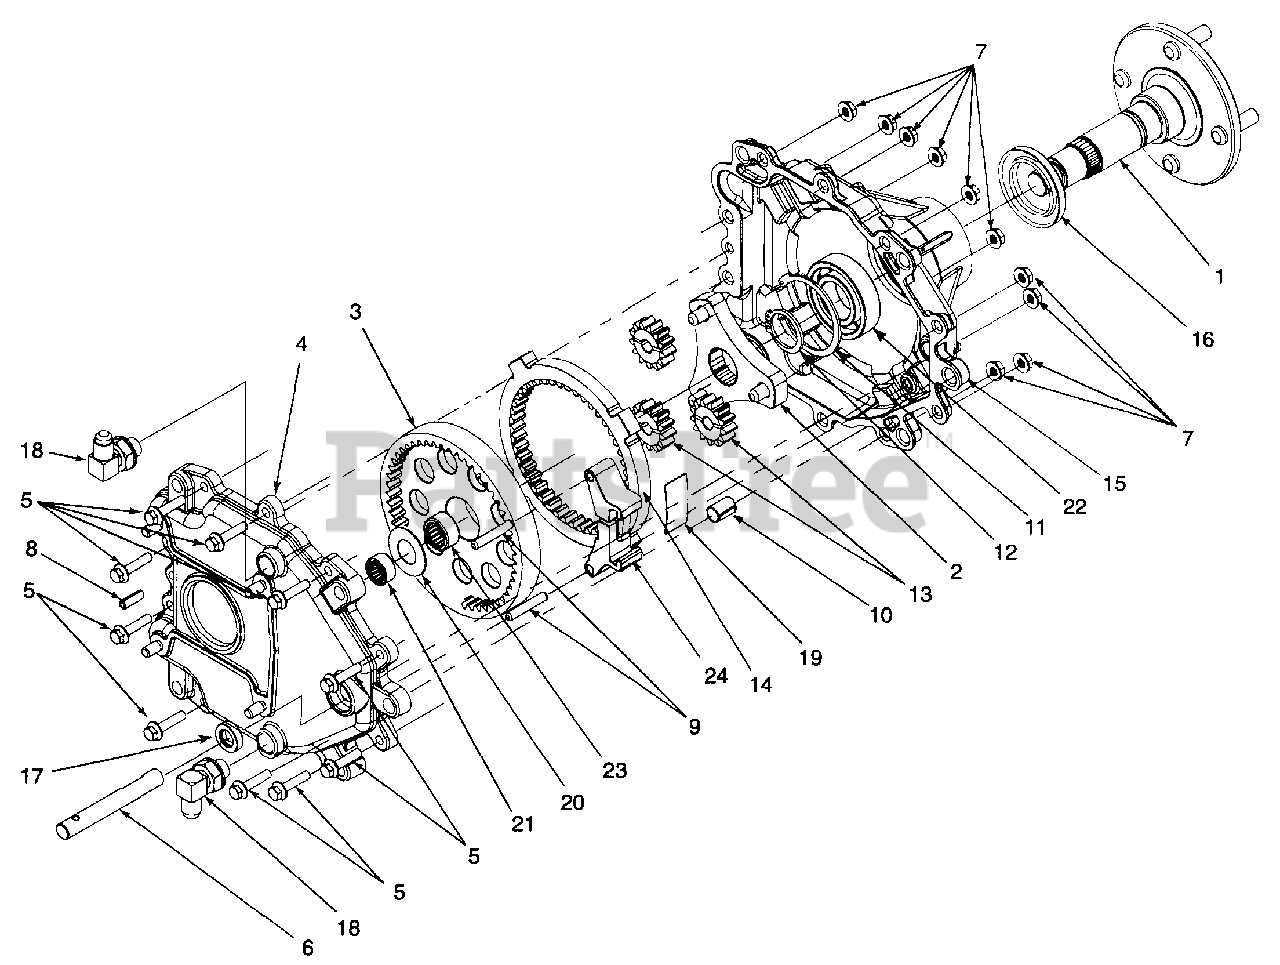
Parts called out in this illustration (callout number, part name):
1	Axle Assembly Stud, Ribbed Neck
2	Carrier Assembly, Output
3	Gear Assembly, 51T Internal & 20T
4	Housing Ass'y, Inner
5	Screw, Hex Wash. Hd. 1/4-20 x 1-1/8
6	Shaft, Brake
7	Nut, Hex Flange Lock, 1/4-20
8	Pin, Roll, .25 x .75
9	Pin, Dowel, .250 x 1.50
10	Bushing, Dowel
11	Ring, Inverted Retaining
12	Ring, Snap, 1.189 Dia. Shft.
13	Gear, Spur, 13T
14	Gear, Ring, 46T
15	Housing
16	Seal, Oil
17	Seal, Oil
18	Fitting, Elbow, 3/8 x 3/8
19	Spring, Brake Shoe
20	Washer, Shim, .76 x 1.5 x .030
21	Bearing, Needle
22	Bearing, Ball
23	Bearing, Needle
24	Brake Shoe
